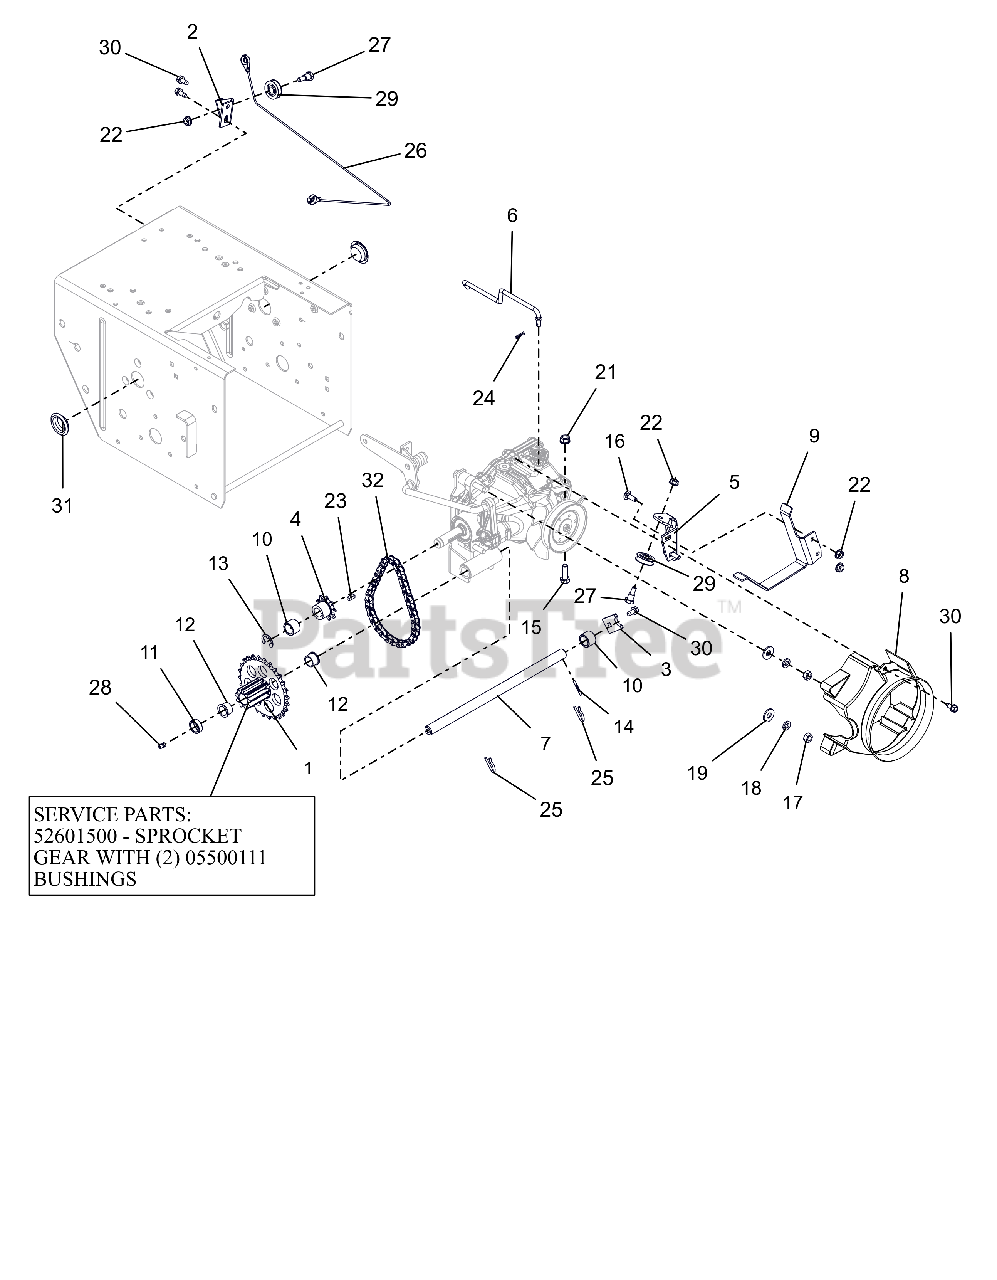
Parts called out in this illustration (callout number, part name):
1	PINION & SPROCKET
1	PINION & SPROCKET W/BUSHINGS
2	BRACKET, CABLE PULLEY
3	TAB, ANTI ROTATION
4	SPROCKET, PINION 9T W/KEY
5	BRACKET, CLUTCH CABLE
6	ROD, HYDRO BYPASS
7	SHAFT, PINION - HARDENED
8	SHROUD, HYDROGEAR RT-310
9	FINGER, BELT - FLAT
10	SPACER, .635X.880X.611
11	BSHG-SLV, .635X.880X.305
12	BSHG-FLG .625X.750X.500X.875
13	RG-RTNG-EXT .625X.042
14	@PIN-GRV .125X1.00 TP E ALLOY
15	BLT,HEX .31-18X1.00 G5 ZCC
16	BLT, RHSN .25-20X.750 G5 ZCC
17	NUT, HEX .312-18 ZCC
18	WSHR, LK-HVY .312X.097 ZCC
19	WSHR,FLT .375X.875X.083 ZCC
21	NUT-LK-TOP-FLG .312-18 GF ZCC
22	NUT-LK-TOP-FLG .250-20 GF ZCC
23	KEY-SQ .187 X .50 X .187
24	PIN, HAIR #178 .06X.77 ZCC
25	PIN, SPRING CLIP
26	CABLE, TRACTION, HYDRO PRO
27	BOLT, SHLDR-.375X.375X.25-20
28	ZERK,FITTING .25X.125 DRIVE IN
29	PULLEY, CABLE
30	SCR-TAP .25-20X.50 HWH ZCC
31	PLUG, HOLE - 1.125"
32	CHAIN - #41, 32 PITCHES
